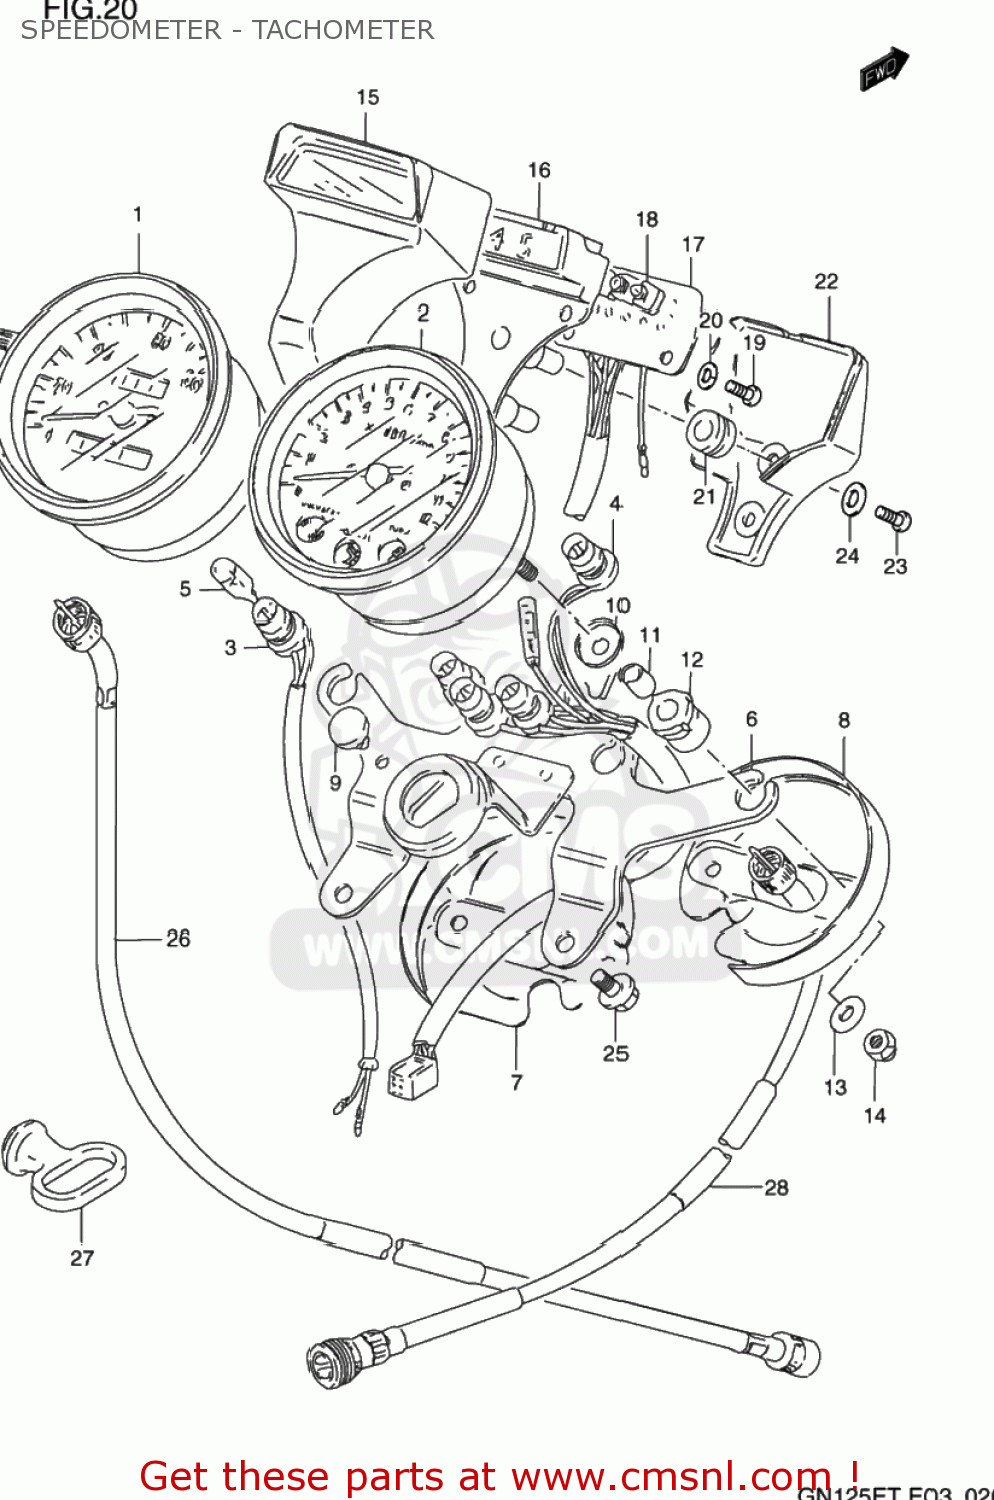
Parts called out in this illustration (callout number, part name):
1	METER,SPEED (KM/MPH)
2	TACHOMETER
3	SOCKET,SPEEDOMETER
4	SOCKET,TACHOMETER
5	BULB(12V3.4W,T10,BF175-01450A)
6	BRACKET,METER
7	UNDER COVER,SPEEDOMETER
8	UNDER COVER,TACHOMETER
9	CUSHION,METER
10	WASHER
11	SPACER,SPEEDOMETER
12	CUSHION,METER
13	WASHER,METER
14	NUT
15	PILOT BOX
16	CASE,PILOT BOX
17	INDICATOR,GEAR POSITION
18	BULB(14V1.12W)
19	SCREW
20	WASHER,LOCK
21	CUSHION
22	COVER,LWR
23	SCREW,
24	WASHER
25	BOLT
26	CABLE ASSY,SPEEDOMETER
27	GUIDE,CABLE
28	CABLE ASSY,TACHOMETER
